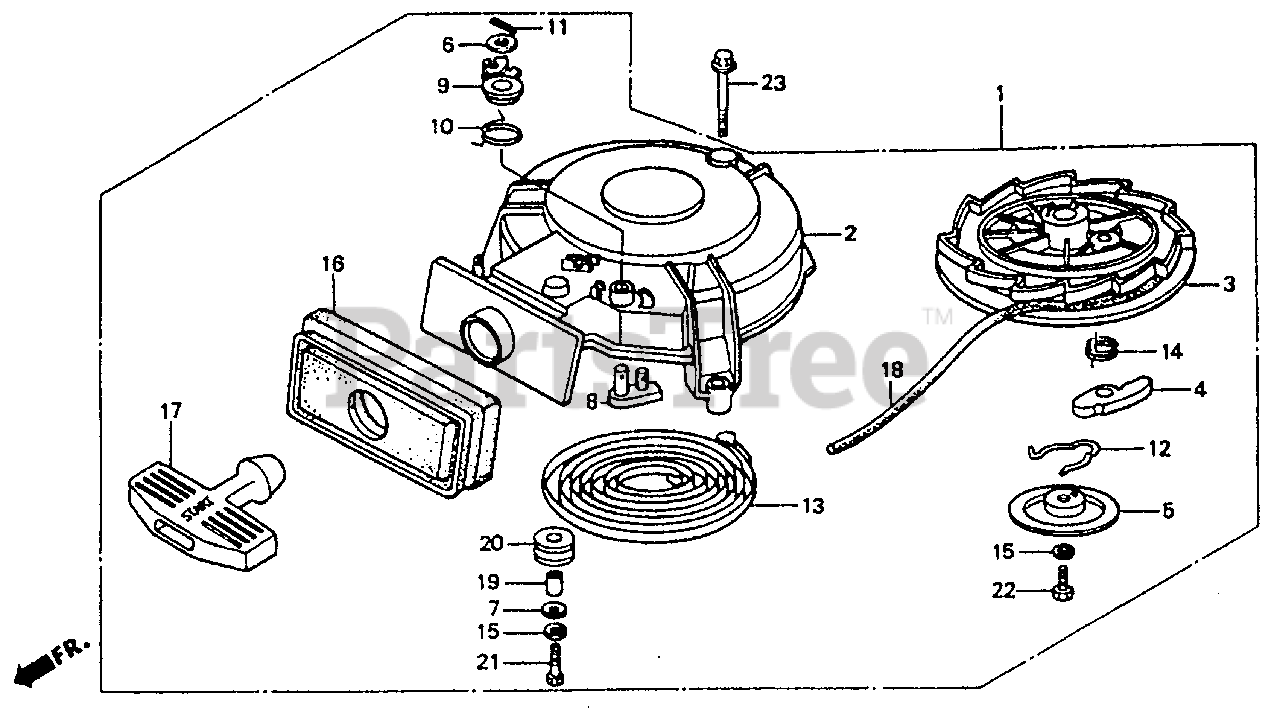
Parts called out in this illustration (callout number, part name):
1	STARTER ASSY., RECOIL
2	CASE, RECOIL STARTER
3	REEL, RECOIL STARTER
4	RATCHET, STARTER
5	PLATE, FRICTION
7	WASHER, THRUST
8	STOPPER, REEL
9	ARM, STOPPER
10	SPRING, STOPPER
11	PIN, SPLIT
12	SPRING, FRICTION
13	SPRING, RECOIL STARTER
14	SPRING, RETURN
15	WASHER, SPRING
16	SEAL, RECOIL
17	KNOB, STARTER
18	ROPE, RECOIL STARTER (#5X73") (N/A: USE P/N 08550-ZG921-11)
19	GUIDE, ROLLER
20	ROLLER, STARTER
21	BOLT, HEX. (6X25)
22	BOLT, HEX. (6X14)
23	BOLT, FLANGE (6X30)
